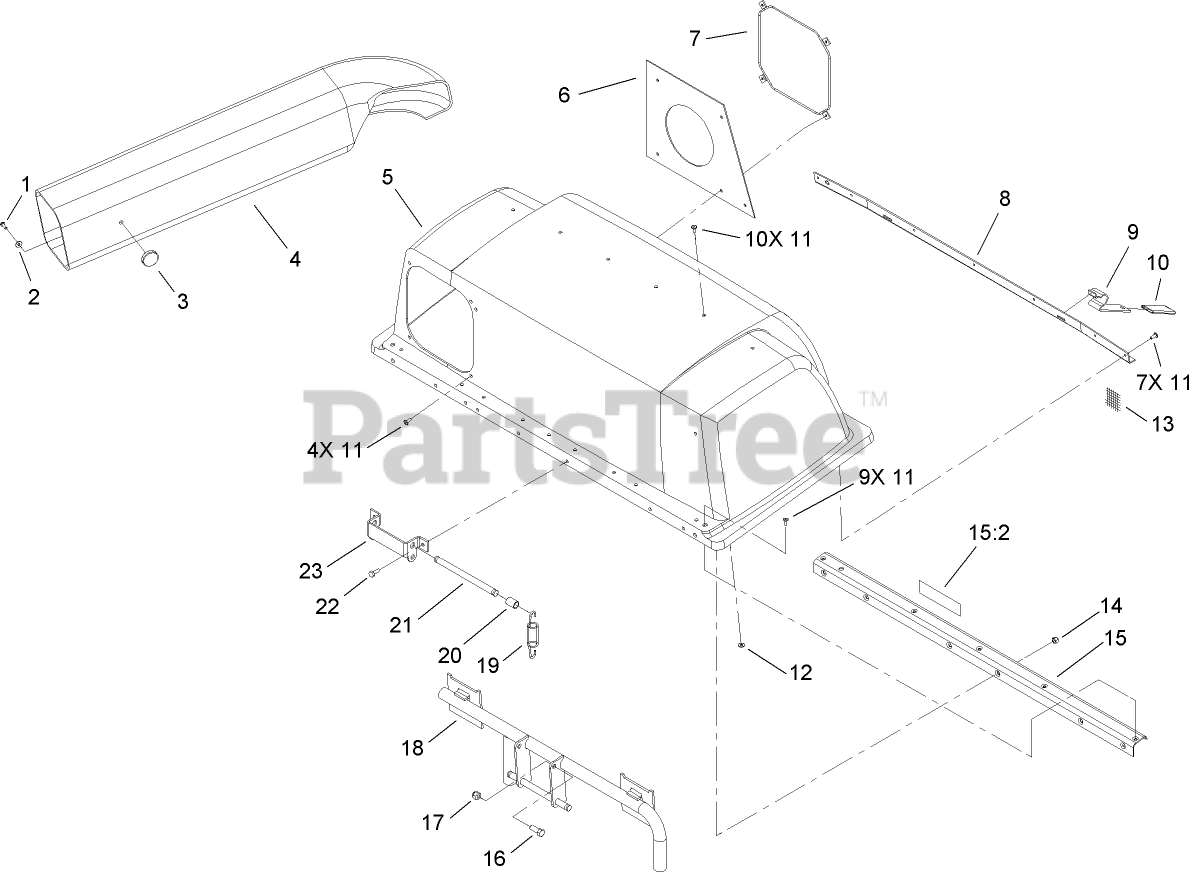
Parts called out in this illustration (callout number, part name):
1	SCREW-PPHTF
2	WASHER-PLAIN
4	CHUTE-DISCHARGE
5	TOP-BAGGER
6	SEAL-CHUTE
7	CLAMP-SEAL
8	SUPPORT-SCREEN
9	LATCH-BAGGER, TOP
11	RIVET-BLIND
12	WASHER-FLAT
13	SCREEN-BAGGER
14	NUT-LOCK, NI
15	STIFFENER ASM
15:2	DECAL-CAUTION
16	SCREW-HH
17	NUT-LOCK, NI
18	FRAME ASM
19	SPRING-EXTENSION
20	SPACER
21	PIN-SPRING
22	SCREW-HH
23	HINGE-BAG, TOP
